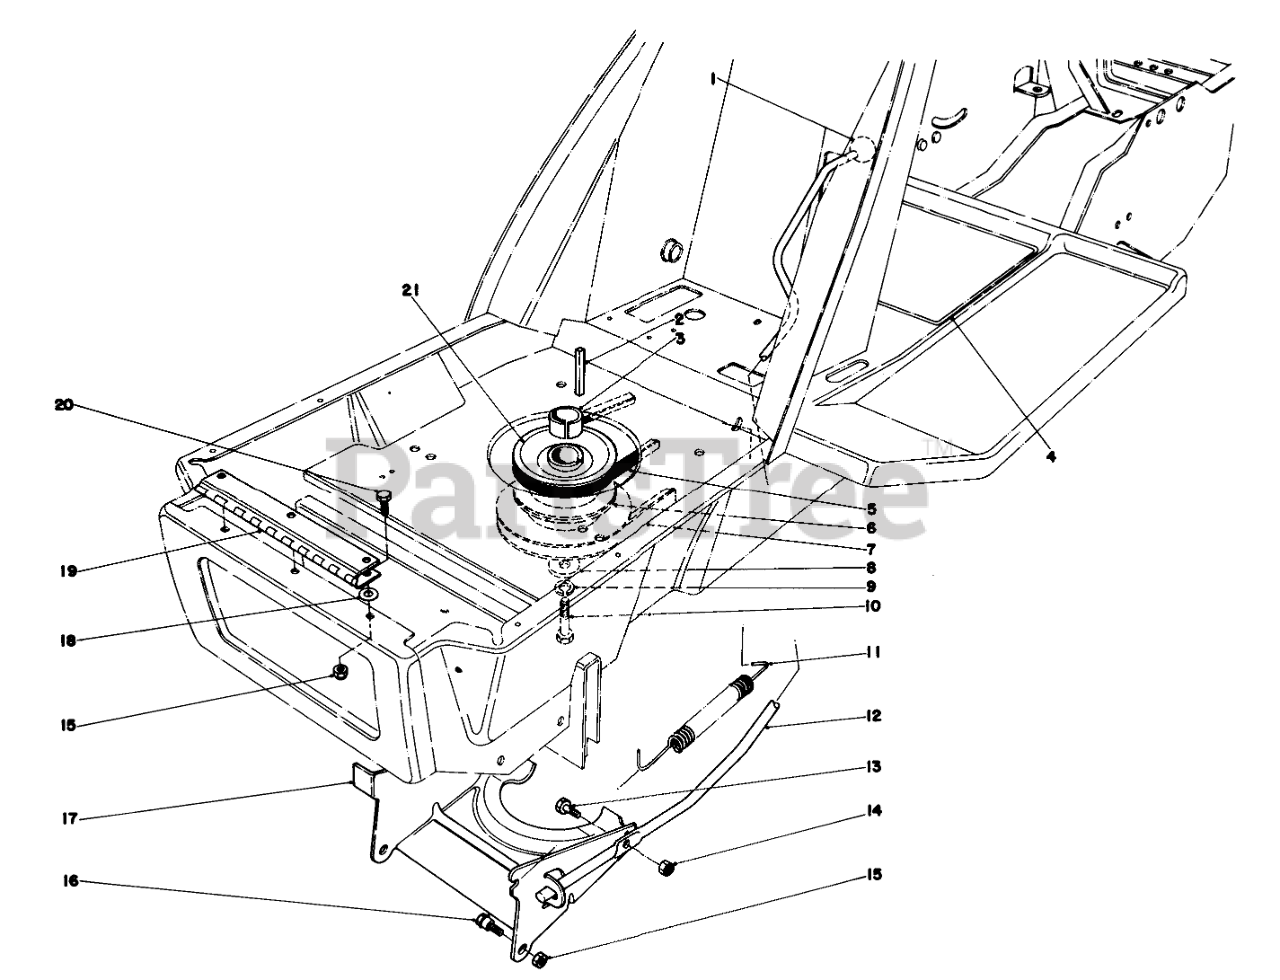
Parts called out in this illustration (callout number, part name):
2	KEY-SQUARE
3	PULLEY SPACER
4	Decal Instruction
5	V BELT
6	Clutch & Brake-Deck
7	V BELT
8	WASHER
9	WASHER-LOCK
10	SCREW-HH
11	TRACTION SPRING
12	Engagement Lever-Clutch Actuator
13	SCREW-HH
14	NUT-LOCK, CONE
15	NUT-LOCK, CONE
16	SCREW-SHOULDER
17	Actuator Clutch
18	WASHER-FLAT
19	Hinge
20	SCREW-HH
21	TOP SHEAVE
